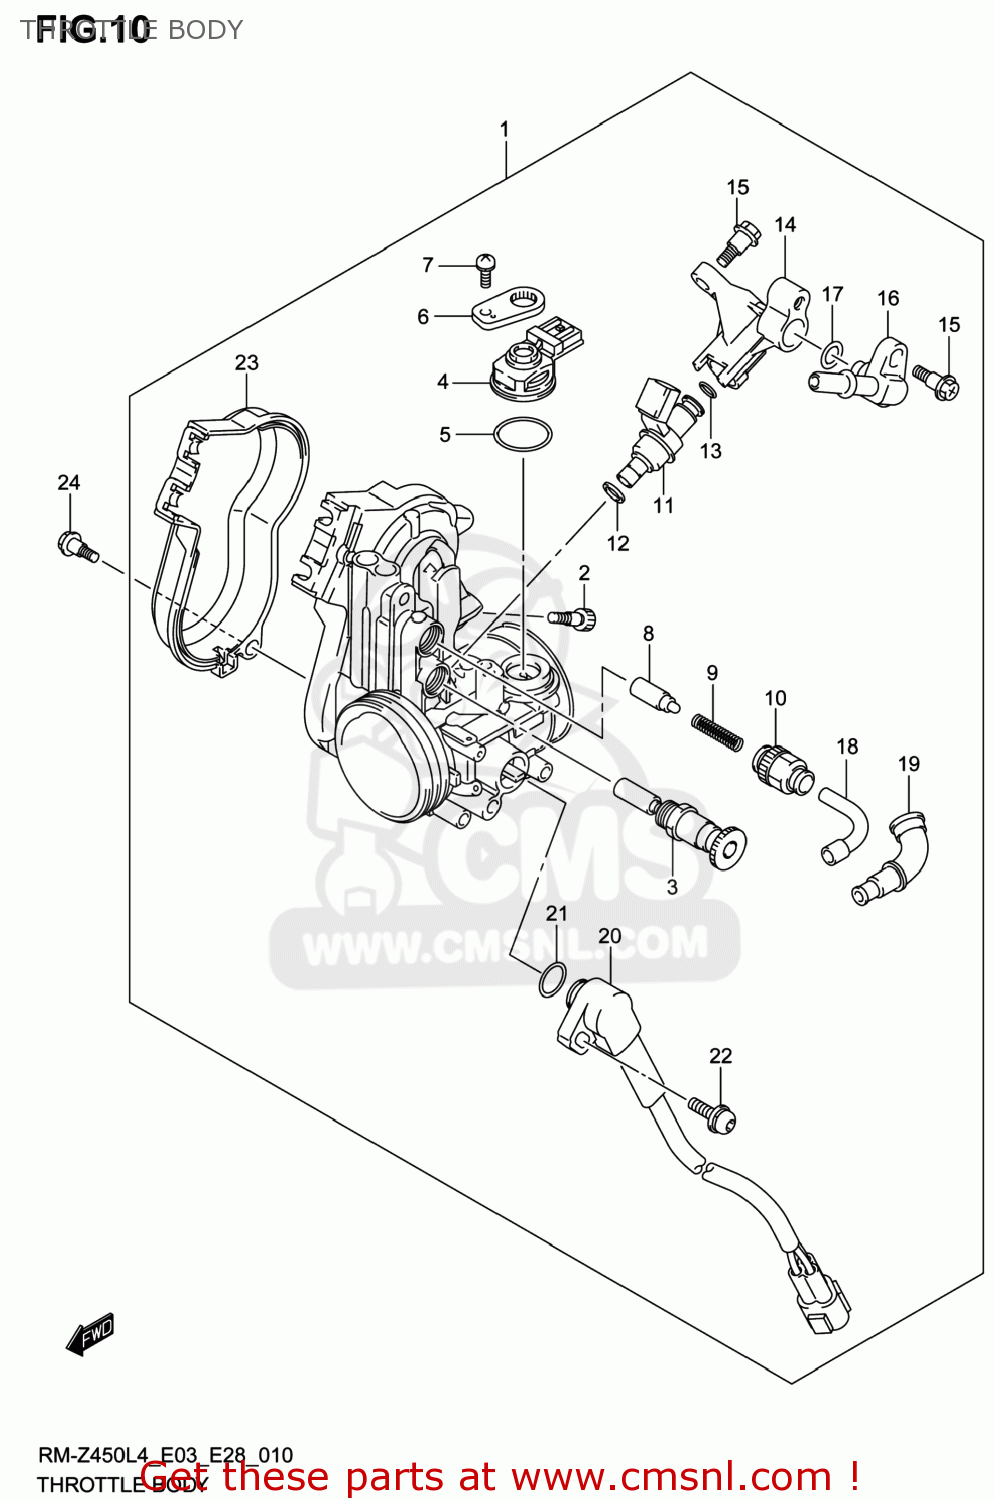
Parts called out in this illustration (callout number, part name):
1	BODY ASSY,THROTTLE
2	SCREW
3	STARTER
4	SENSOR,MAP
5	O RING
6	PLATE,STAY
7	SCREW
8	VALVE,STARTER
9	SPRING
10	HOLDER,CABLE
11	INJECTOR ASSY
12	RING,SEAL
13	O RING
14	PIPE,FUEL
15	SCREW
16	JOINT
17	O RING
18	GUIDE,CABLE
19	CAP
20	SENSOR ASSY,THROTTLE
21	O RING
22	SCREW
23	COVER
24	SCREW
